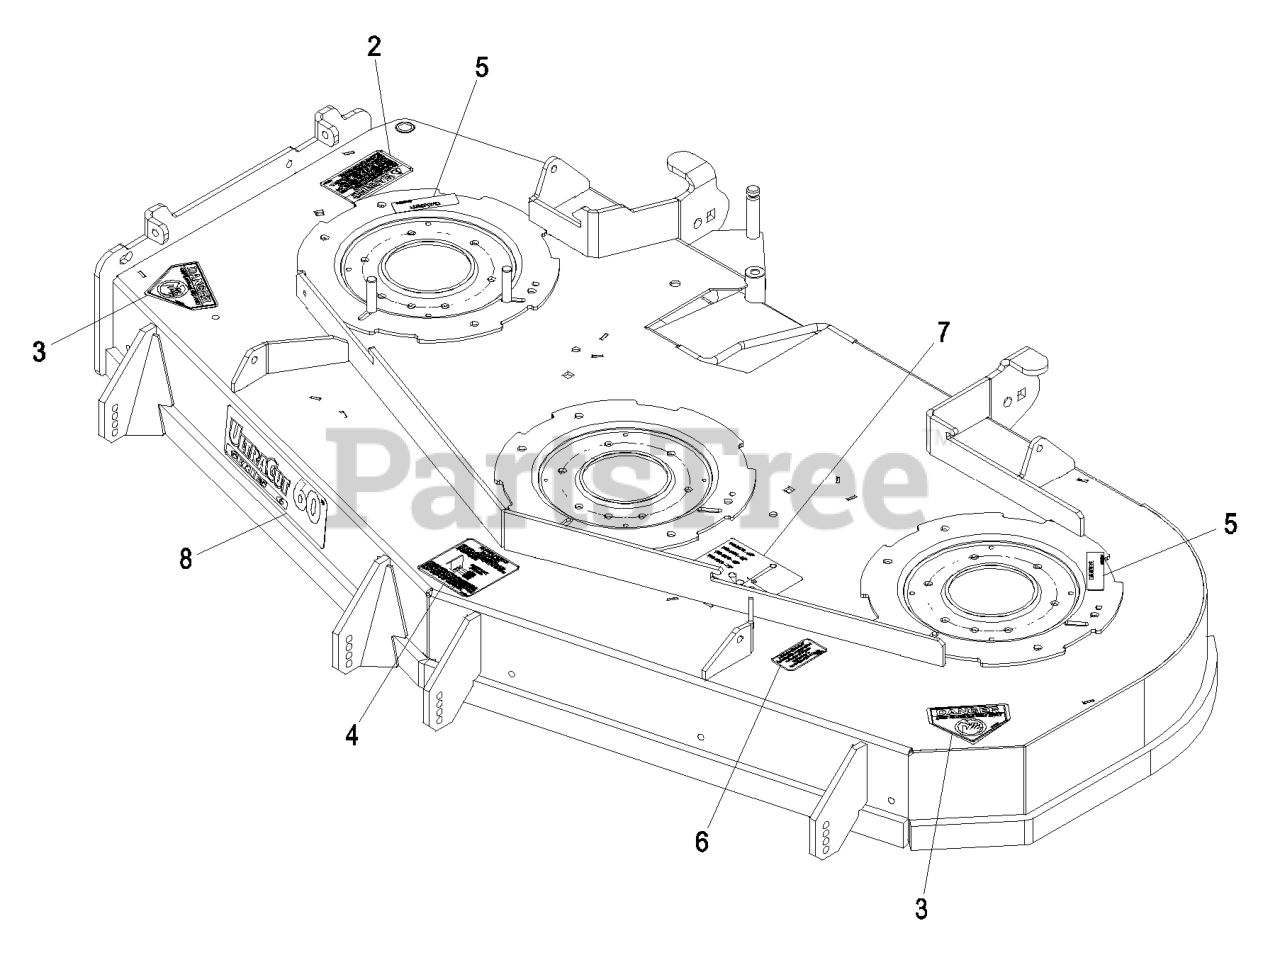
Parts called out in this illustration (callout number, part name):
2	DECAL-WARNING, DISCHARGE
3	DECAL-DANGER
4	DECAL,ANTISCALP
5	DECAL-COVER, MISSING
6	DECAL,BOLT TORQUE
7	DECAL,BELT ROUTING
8	DECAL,ULTRACUT 60 SERIES
